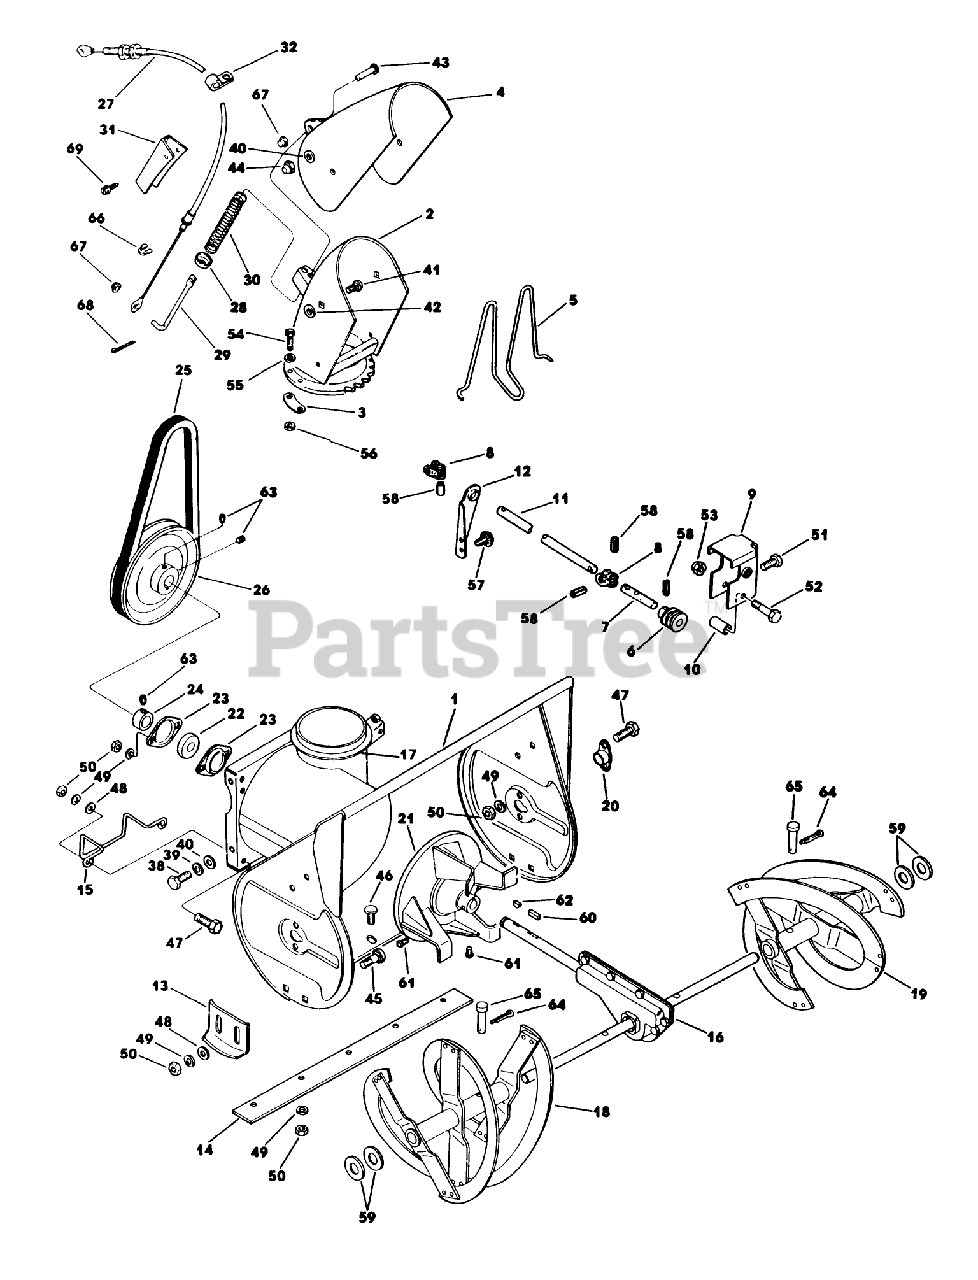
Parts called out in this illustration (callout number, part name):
3	HOLD DOWN CHUTE
14	SCRAPER BLADE *B
15	LWR AUGER BELT GUIDE
18	AUGER ASSEM R/B 744444
19	LH AUGER AY
22	DISCONTINIUED
23	FLANGETTE-BEARING
26	PULLEY ASM
44	NUT-LOCKING
45	BOLT - CARRIAGE
47	SCREW - HEX
53	NUT-LOCK, CONE
55	WASHER - LOCKING
57	SCREW-HWH
63	SET SCREW
65	PIN-SHEAR
66	RET. RING
69	SCREW S
